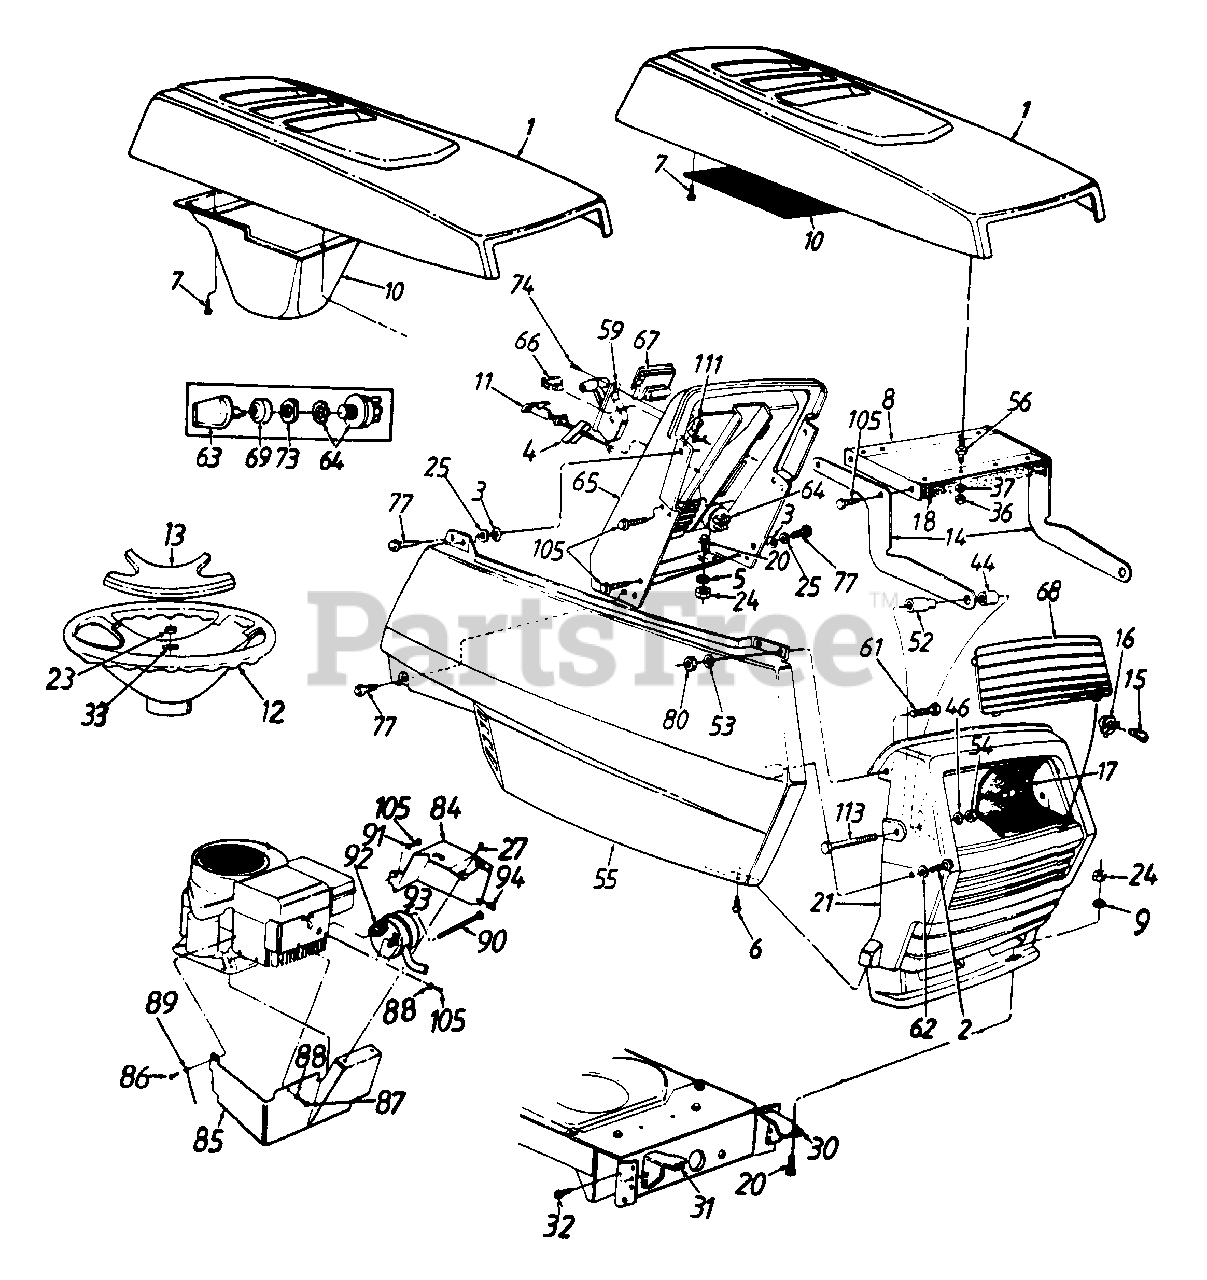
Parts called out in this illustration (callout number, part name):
3	Bolt Retainer 1/4" I.D.
4	Retainer Clip
5	Fl-Wash..34" I.D. x .68"
6	Truss Mach. B-Tap Scr. #10 x,5" Lg.
7	Hex Wash Hd. AB-Tap Scr. 08 x .5" Lg.
10	Air Ducts
11	Choke Control 29" Lg.
12	Steering Wheel
13	Steering Wheel Cap
14	Hood Hinge
15	Lamp
16	Twist Lock - Lamp Socket
17	Reflector - Headlight
18	Foam Seal
20	Hex Bolt 5/16-18 x .75" Lg.
23	Hex L-Nut 5/16-24 Thd.
24	Hex Nut 5/16-18 Thd.
25	Fl-Wash. 1/4" I.D. x .93" O.D.
27	Hex B-Tap Scr. #10 x .38" Lg.
30	Grille Mount Brk't.- L.H.
31	Grille Mount Brk't.- R.H.
32	Hex Wash. Hd. AB-Tap Scr. 5/16 x .75" Lg.
33	Bell-Wash..345" I.D. x .88"
36	Hex Nut 1/4-20 Thd.
37	Bell-Wash..265" I.D. x.75"
44	Spacer .33" I.D. x .625" O.D.
46	Fl-Wash..328" I.D. x .68" O.D.
52	Shld. Spacer .33" I.D.
53	Fl-Wash..281" I.D. x .5" O.D.
54	Hex Cent. L-Nut 5/16-18 Thd.
55	Side Cover - R.H.
56	Double Ended Stud 1/4-20 Thd.
61	Hex Bolt 1/4-20 x .62" Lg.
62	Fl-Wash..281" I.D. x .73" O.D.
63	Ignition Key
64	Ignition Switch
65	Dash Panel
66	Light Switch
67	Ammeter
68	Lens (White Logo)
69	Ignition Switch Cap
73	Ignition Switch Nut
74	Truss Mach. AB-Tap Scr. #10 x .5" Lg.
77	Hex Wash. Hd. Tap Scr. 1/4 x .75" Lg.
80	Hex L-Nut 1/4-20 Thd.
84	Muffler Heat Shield - L.H.
85	Muffler Heat Shield - R.H.
86	Pan Hd. Mach. Scr. 5/16-18 x.75" Lg.
87	Hex Bolt 1/4-20 x 3/8" Lg.
88	Spr. Wash..265" I.D.
89	Ground Wired
90	Shld . Bolt 7/16" Dia. x 3-5/8" Lg.
91	L-Wash. 1/4" I.D.
92	Gaskets
93	Muffler
94	Speed Nut #10-24 Thd.
105	Hex Tap Scr. 1/4-20 x .5" Lg.
111	Speed Nut 1/4-20 Thd.
113	Hex Bolt 5/16-18 x 2.75"
